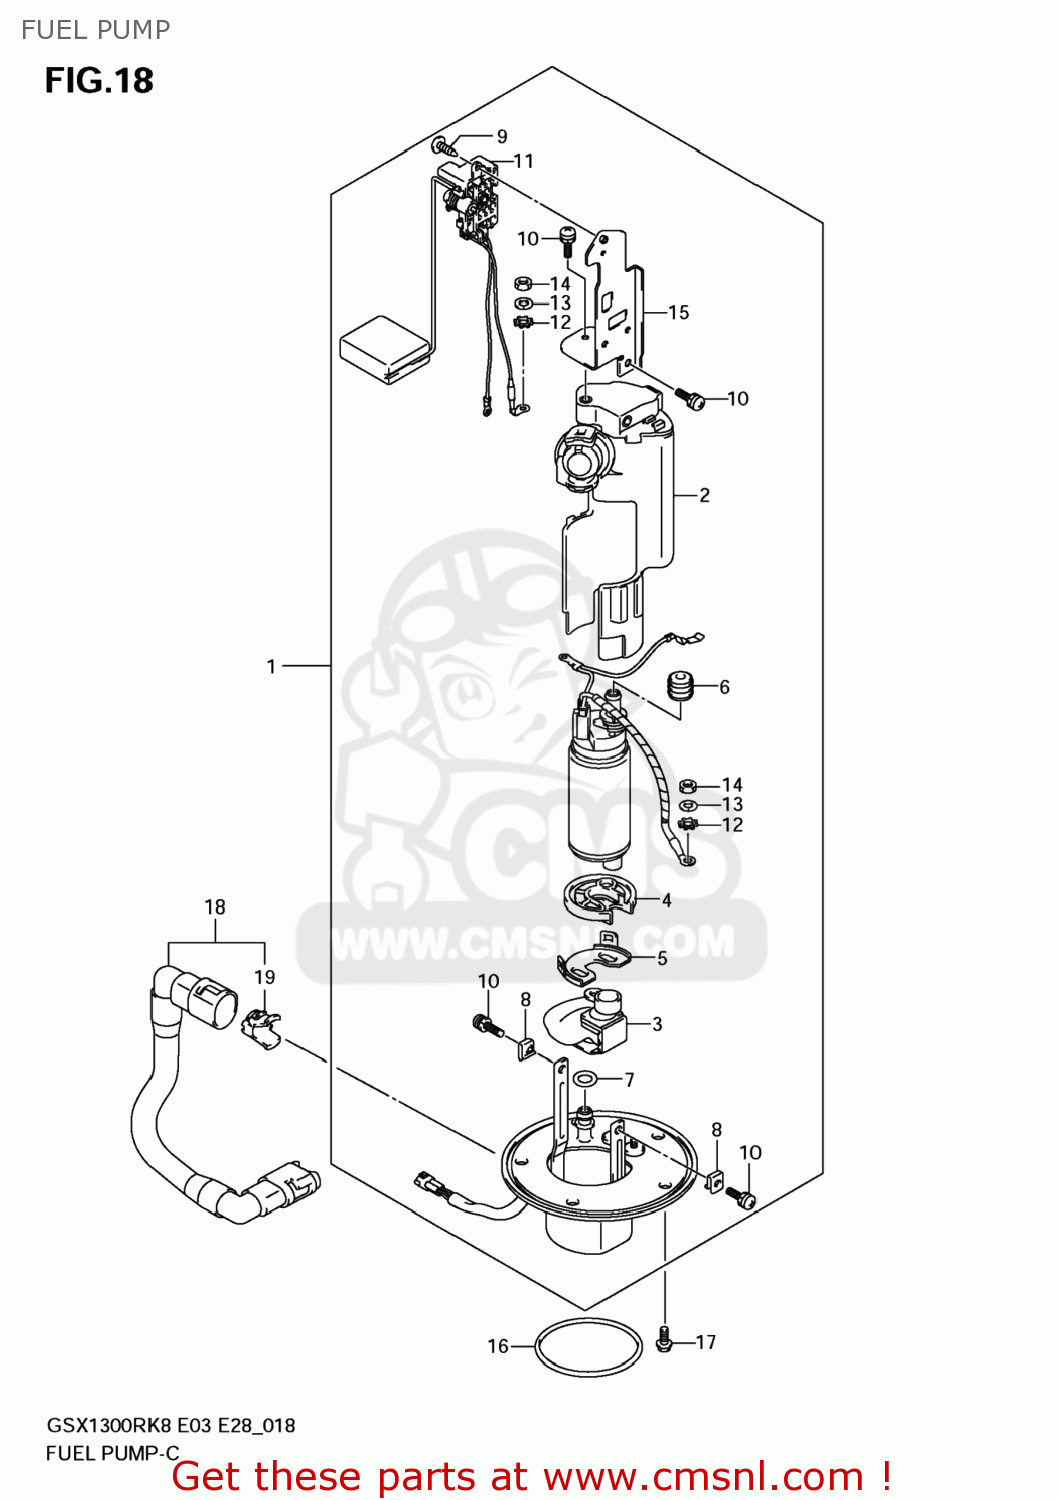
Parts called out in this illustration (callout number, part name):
1	PUMP ASSY,FUEL
2	FILTER,FUEL
3	STRAINER,FUEL
4	CUSHION
5	HOLDER,FUEL PUMP
6	BUSH,FUEL PUMP
7	O RING
8	NUT
9	SCREW
10	SCREW
11	GAUGE ASSY,FUEL LEVEL
12	WASHER
13	WASHER,SPRING
14	NUT
15	BRACKET,FUEL GAUGE
16	O RING,FUEL PUMP
17	BOLT
18	HOSE COMP,FUEL
19	RETAINER
